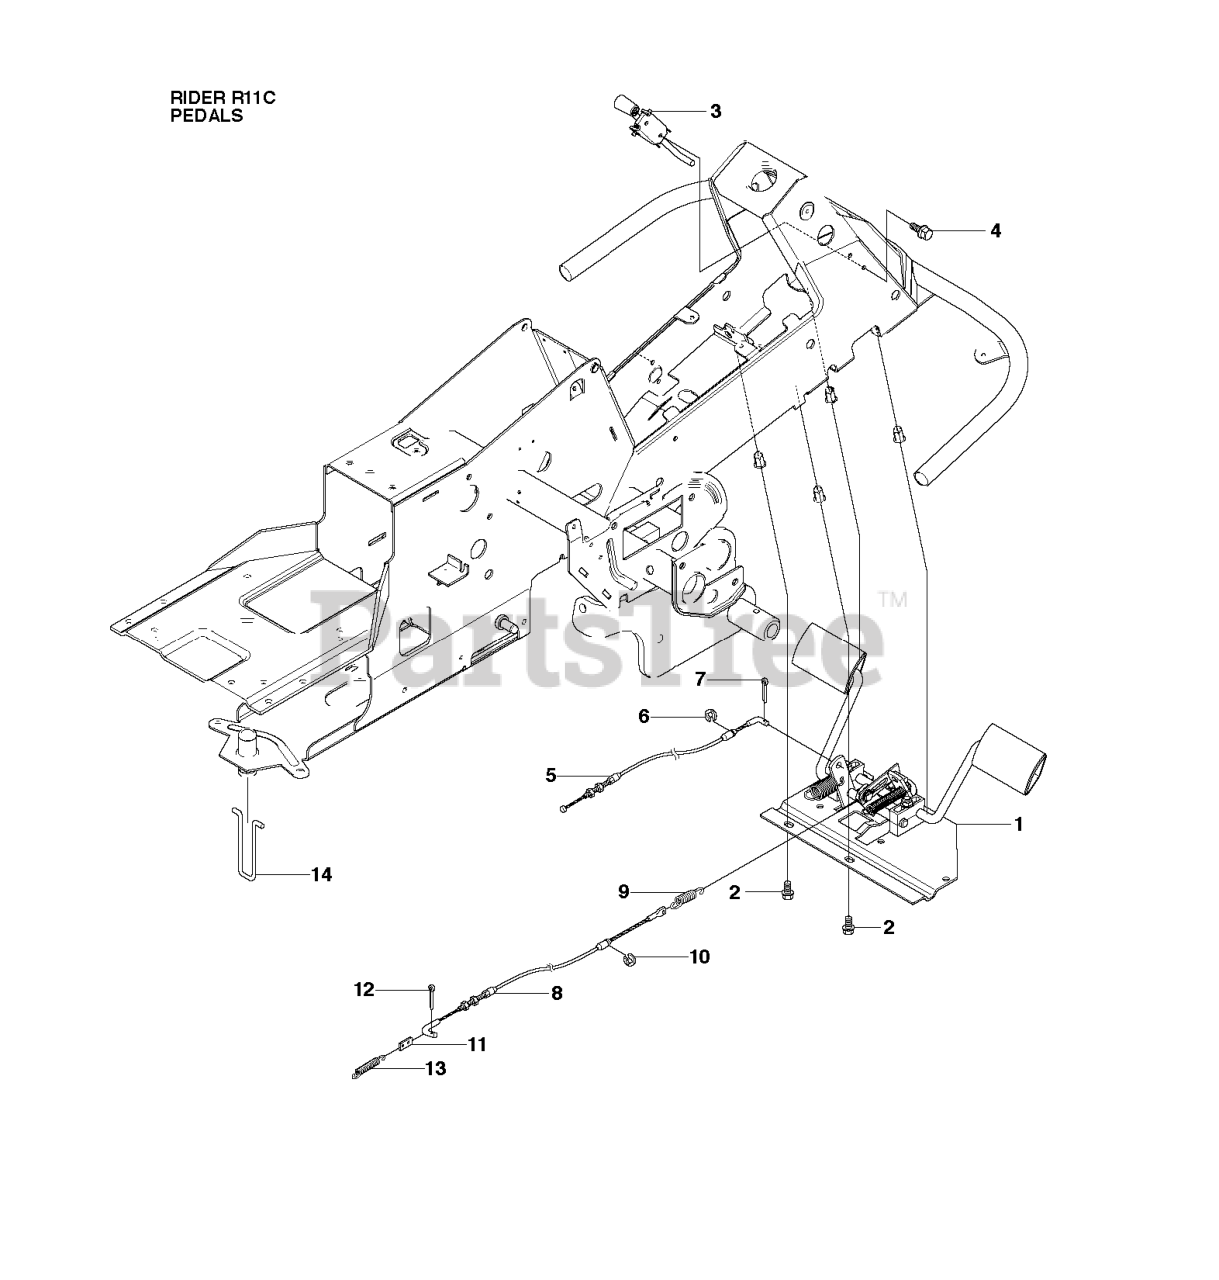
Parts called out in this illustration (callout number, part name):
1	PEDAL PLATE ASSY MANUAL
3	BRAKE LEVER ASSY
7	Cotter Pin
12	Cotter Pin
